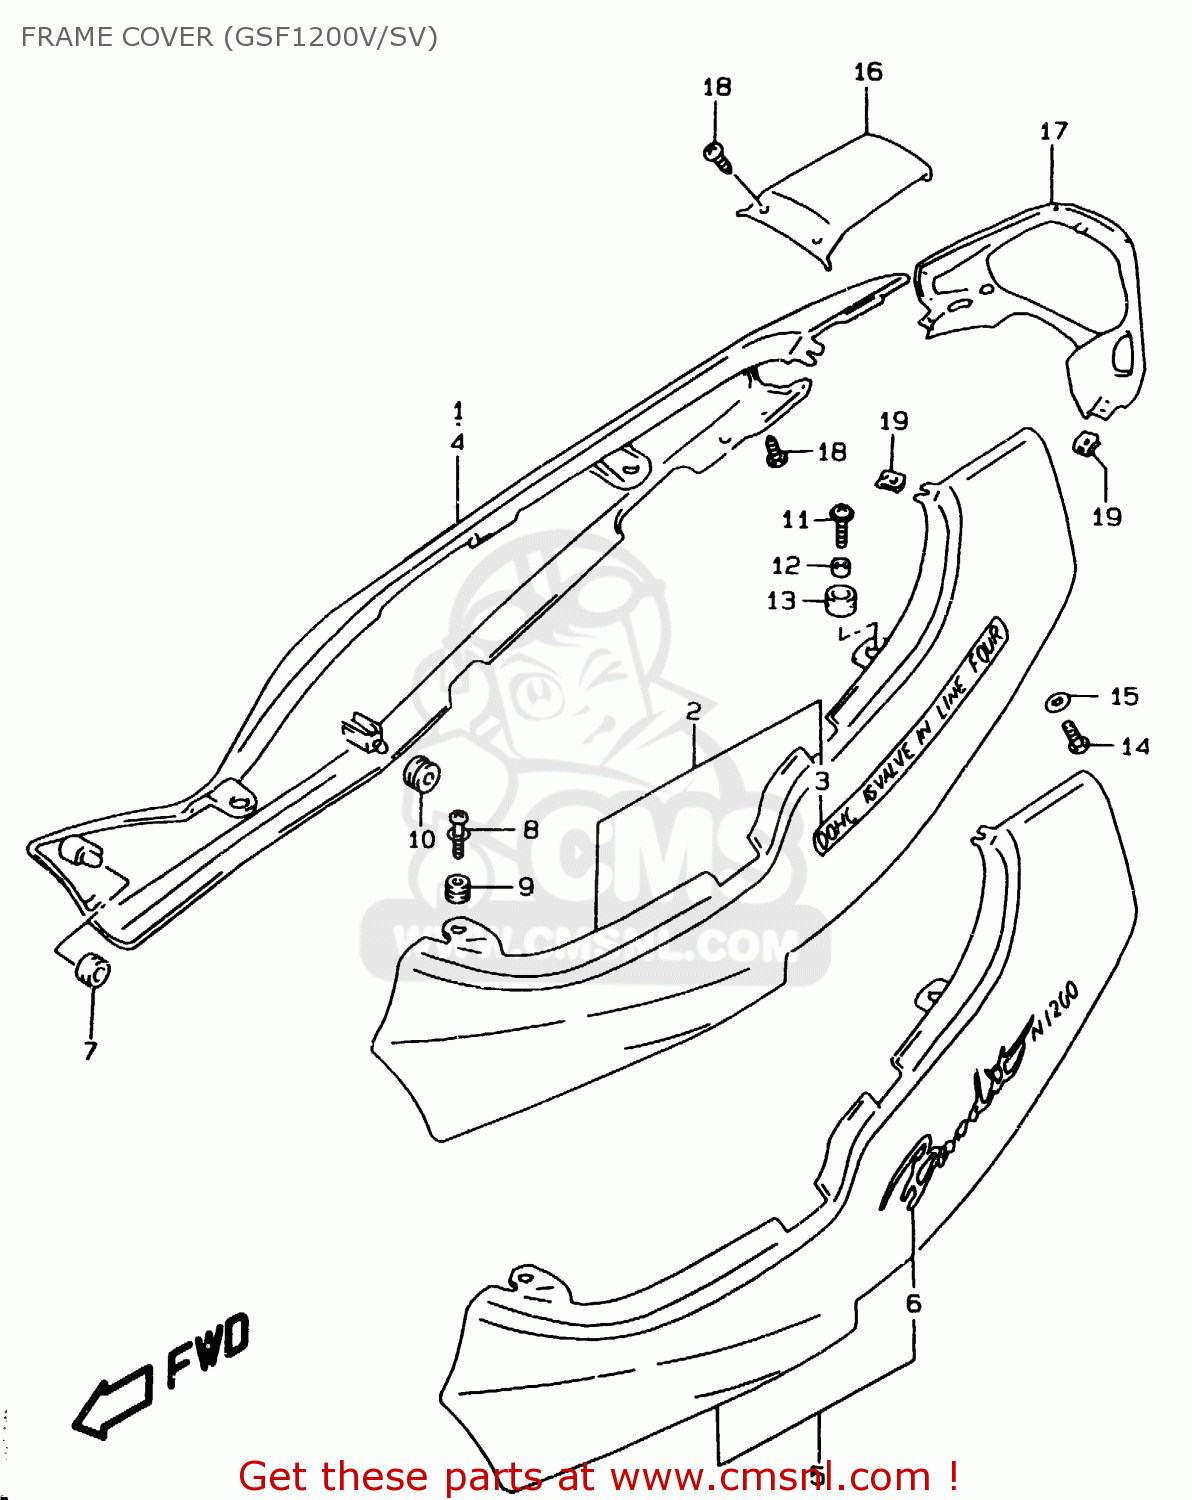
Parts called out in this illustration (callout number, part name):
1	COVER,FRAME,R(BLUE)
2	COVER,FRAME,L(BLUE)
3	EMBLEM,FRAME COVER
4	COVER,FRAME,R(BLACK)
5	COVER,FRAME,L(BLUE)
6	EMBLEM,FRAME COVER
7	CUSHION,FRAME COVER FR
8	CLIP
9	CUSHION
10	CUSHION
11	SCREW(6X20)
12	SPACER(6.5X10X9.4)
13	CUSHION
14	SCREW
15	WASHER(6.3X16X1.5)
16	COVER,FRAME CTR
17	COVER,FRAME RR
18	SCREW
19	NUT
